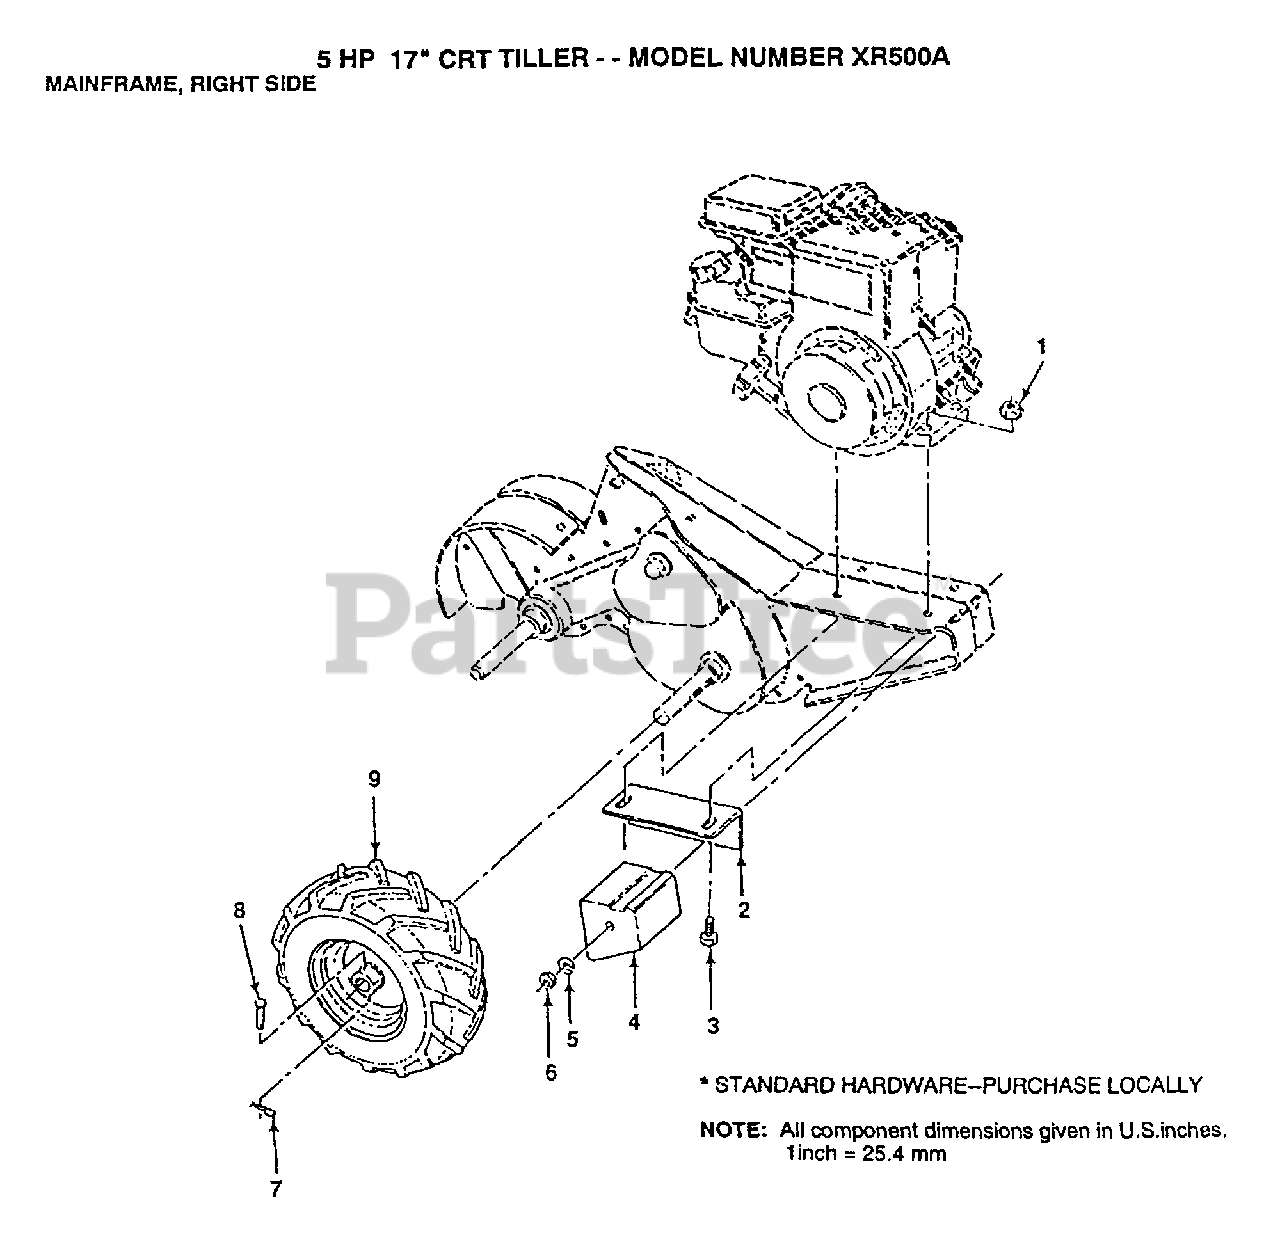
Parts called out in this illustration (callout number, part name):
2	BRACKET RH CRT
3	BOLT.HEX.5/16-1.5
4	COUNTERWEIGHT CRT
5	LOCKWASHER
6	NUT.HEX.3/8-16UNC
7	RETAINER M
8	RIVET.DRILL.1.75
9	TIRE.CHV.13X5.0-6
